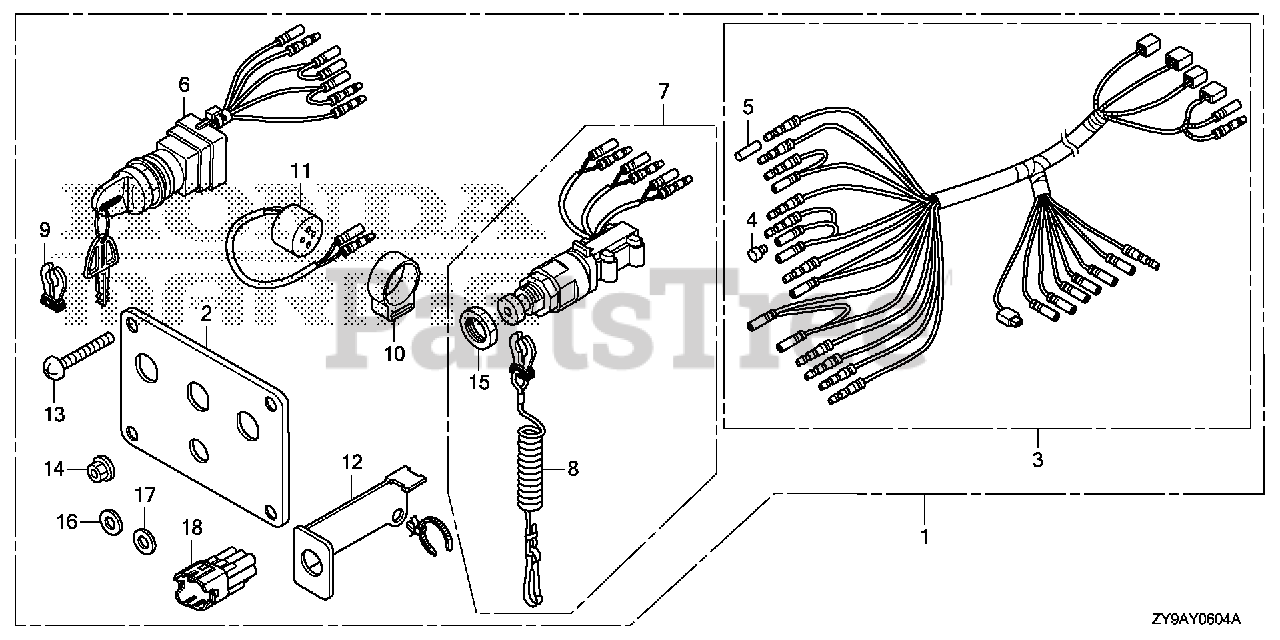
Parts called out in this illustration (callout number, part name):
1	PANEL KIT, SWITCH (TRIPLE)
2	PANEL, CONTROL (TRIPLE)
3	HARNESS ASSY., SWITCH PANEL
4	PLUG, CONNECTOR (INNER) (TROLLING CONTROL)
5	PLUG, CONNECTOR (OUTER) (ENGINE NO.)
6	SWITCH ASSY., COMBINATION
7	SWITCH ASSY., EMERGENCY STOP (TRIPLE)
8	WIRE, EMERGENCY
9	CLIP, EMERGENCY LOCK
10	SUSPENSION, AUDIBLE PILOT
11	BUZZER, WARNING
12	BRACKET
13	SCREW, PAN (5X40) DUAL QTY = (8) (SINGLE)
14	NUT, FLANGE (5MM)
15	NUT
16	WASHER, PLAIN (5MM)
17	WASHER, SPRING (5MM)
18	DUMMY, WATERPROOF CONNECTOR (GREEN)
